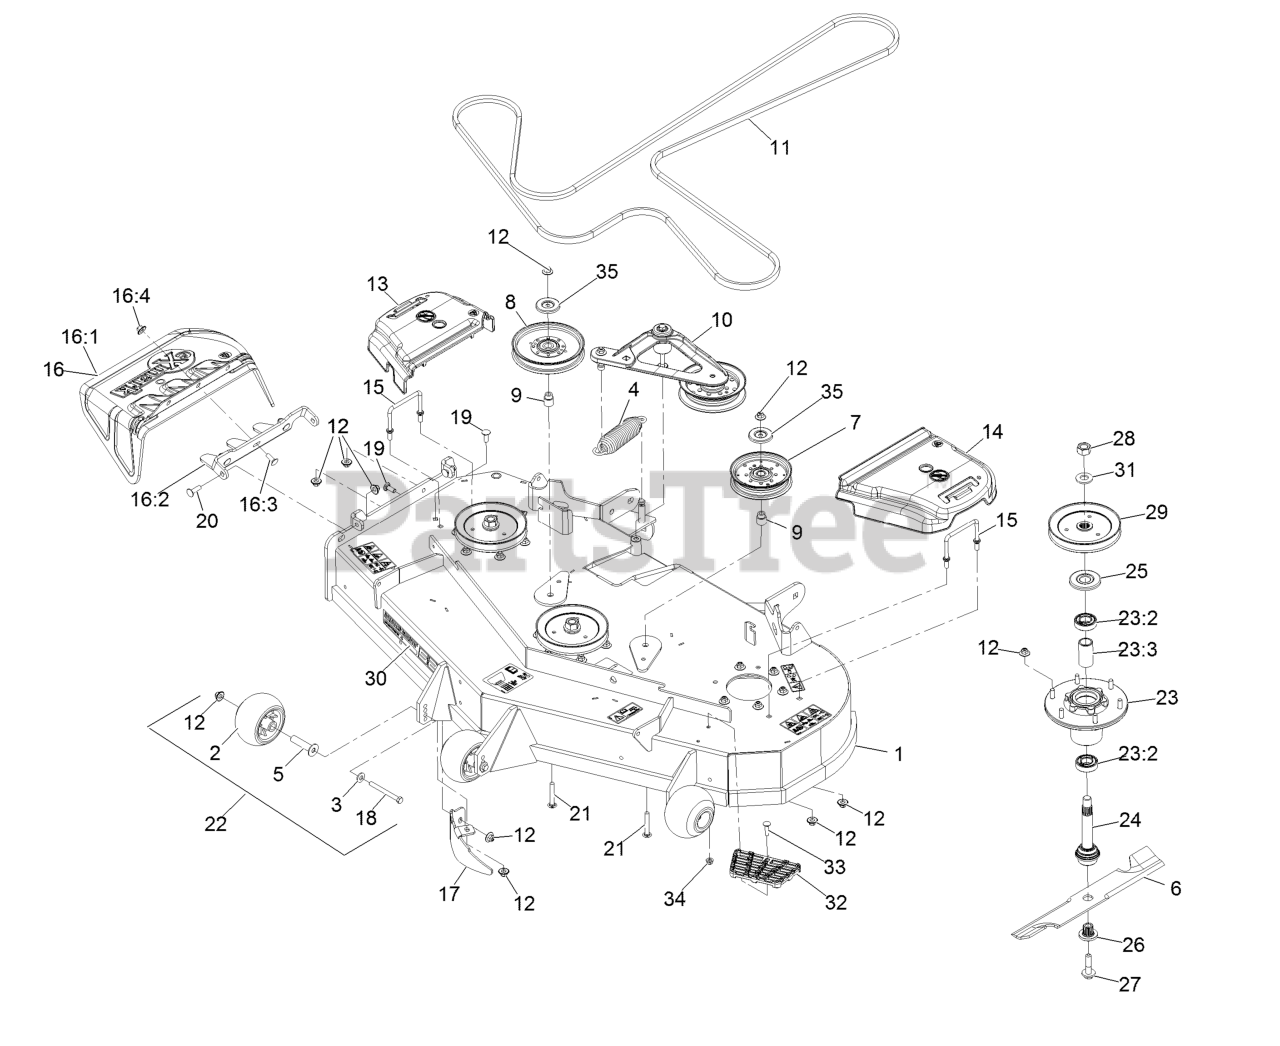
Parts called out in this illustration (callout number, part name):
1	ASM,Deck W/ Decals 52
2	Roller-Anti-Scalp
3	Washer-Spring Disc 3/8
4	Spring-Extension
5	Axle, Roller
6	Blade, Solid
6	Blade, Low Lift
6	Blade, Mulching
6	Blade-Notched
6	Blade-Extreme 2, 18.00"
7	Pulley-Idler, Flat
8	Idler-Pulley
9	Bushing, Idler
10	Deck Idler ASM
11	Belt,V-B X 186.00"
12	Nut-Nyloc 3/8-16 Flg
13	Cover-Belt, RH
14	Cover-Belt, LH
15	Wireform-Cover
16	ASM,Discharge Chute
16:1	Chute, Discharge
16:2	Bracket,Discharge Chute
16:3	Bolt-Carriage 3/8-16 X 1
16:4	Nut-Nyloc 3/8-16 Flg
17	Baffle-Dogleg, Lz-Vt52
18	Screw-HH 3/8-16 X 3 3/4 GR 8
19	Bolt-Carriage 3/8-16 X 1
20	Bolt-Carriage 3/8-16 X 1 1/4
21	Bolt-Carriage 3/8-16 X 2 1/2
22	Kit, Anti-Scalp Roller
23	ASM-Cutter Hsg With Bearings
23:2	Bearing-Ball
23:3	Spacer-Bearing
24	ASM-Spindle And Seal
24	Sub-Contract Bom
25	Guard,Bearing Top .989
26	Bushing, Splined
27	Screw-Sems 1/2-20 X 2.19
28	Nut-Hex
29	Sheave,Blade Drive 6.50
30	Decal, 524
31	Washer-Spring Disc 3/4
32	Step-Deck
33	Bolt-Carriage 5/16-18 X 1 1/4
34	Nut-Nyloc 5/16-18 Flg
35	Shield-Dust
